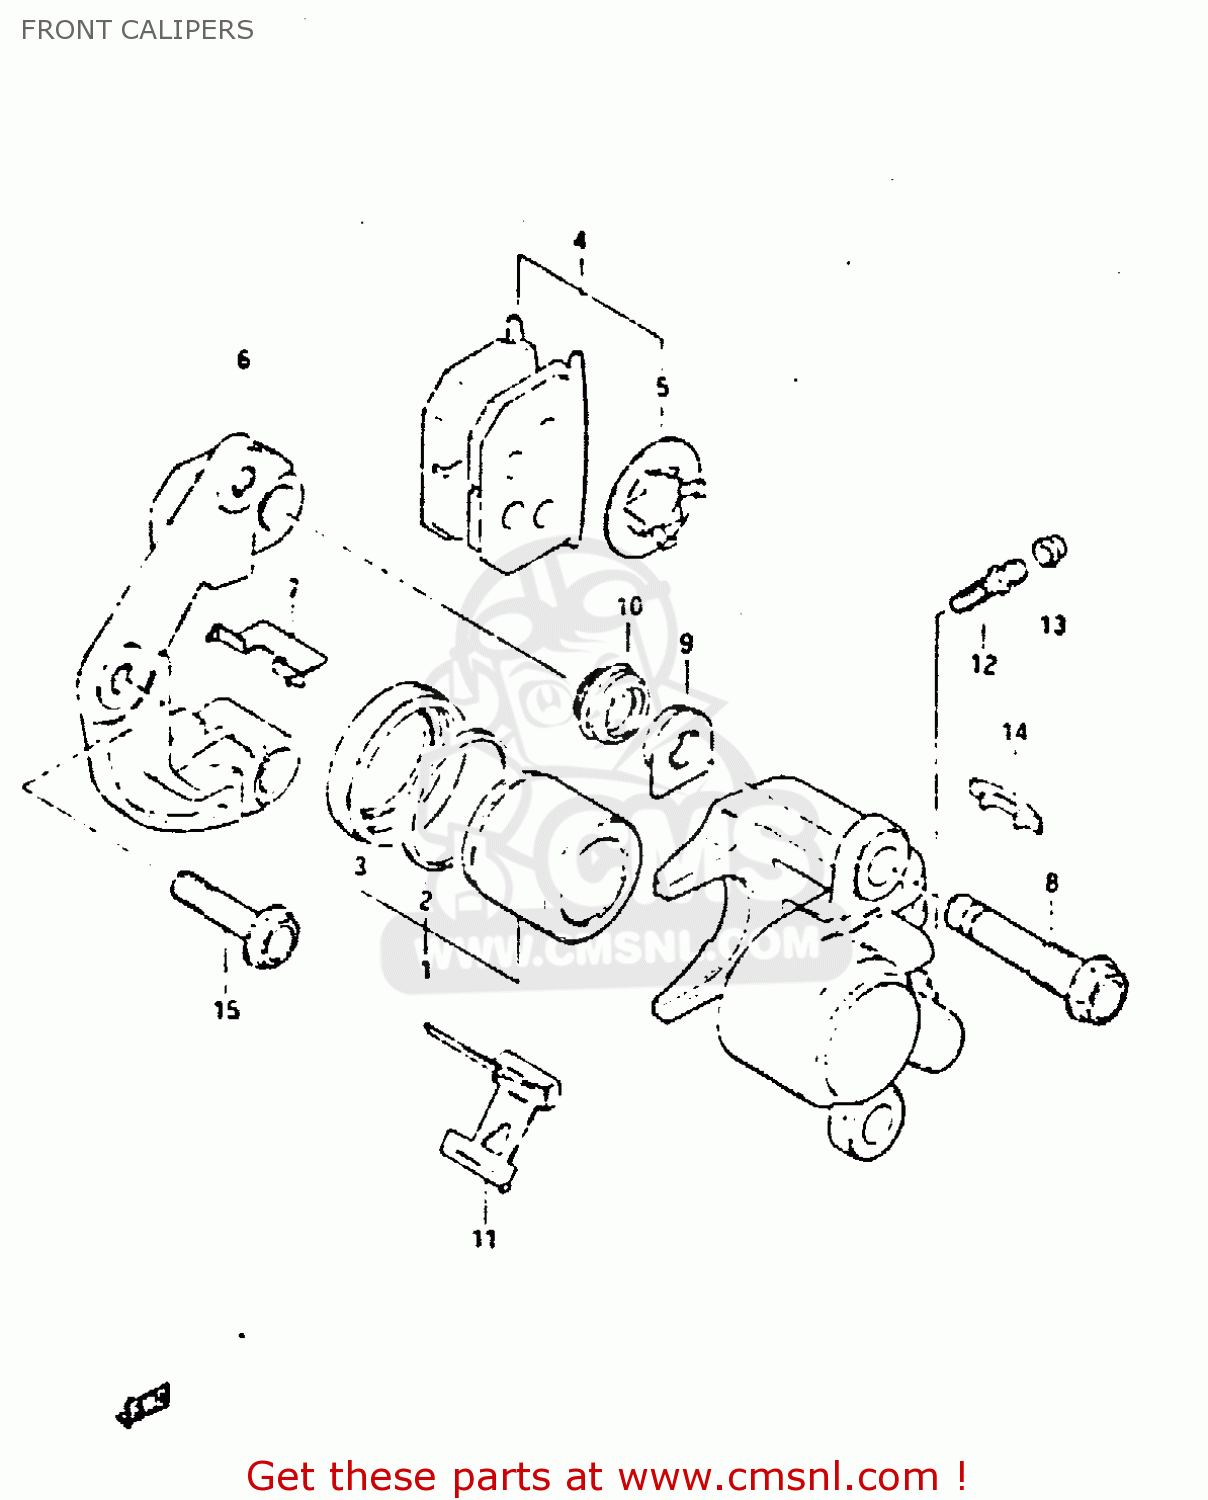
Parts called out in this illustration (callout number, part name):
1	PISTON SET
2	SEAL,PISTON
3	BOOT,PISTON
4	PAD & SHIM SET (MCA)
5	SHIM,PAD
6	HOLDER,CALIPER,LEFT
7	PAD,GUIDE
8	AXLE,CALIPER
9	NUT,CALIPER AXLE
10	BOOT
11	SPRING
12	BREATHER
13	CAP,BLEEDER PL
14	COVER,INDICATOR
15	BOLT(10X37)
